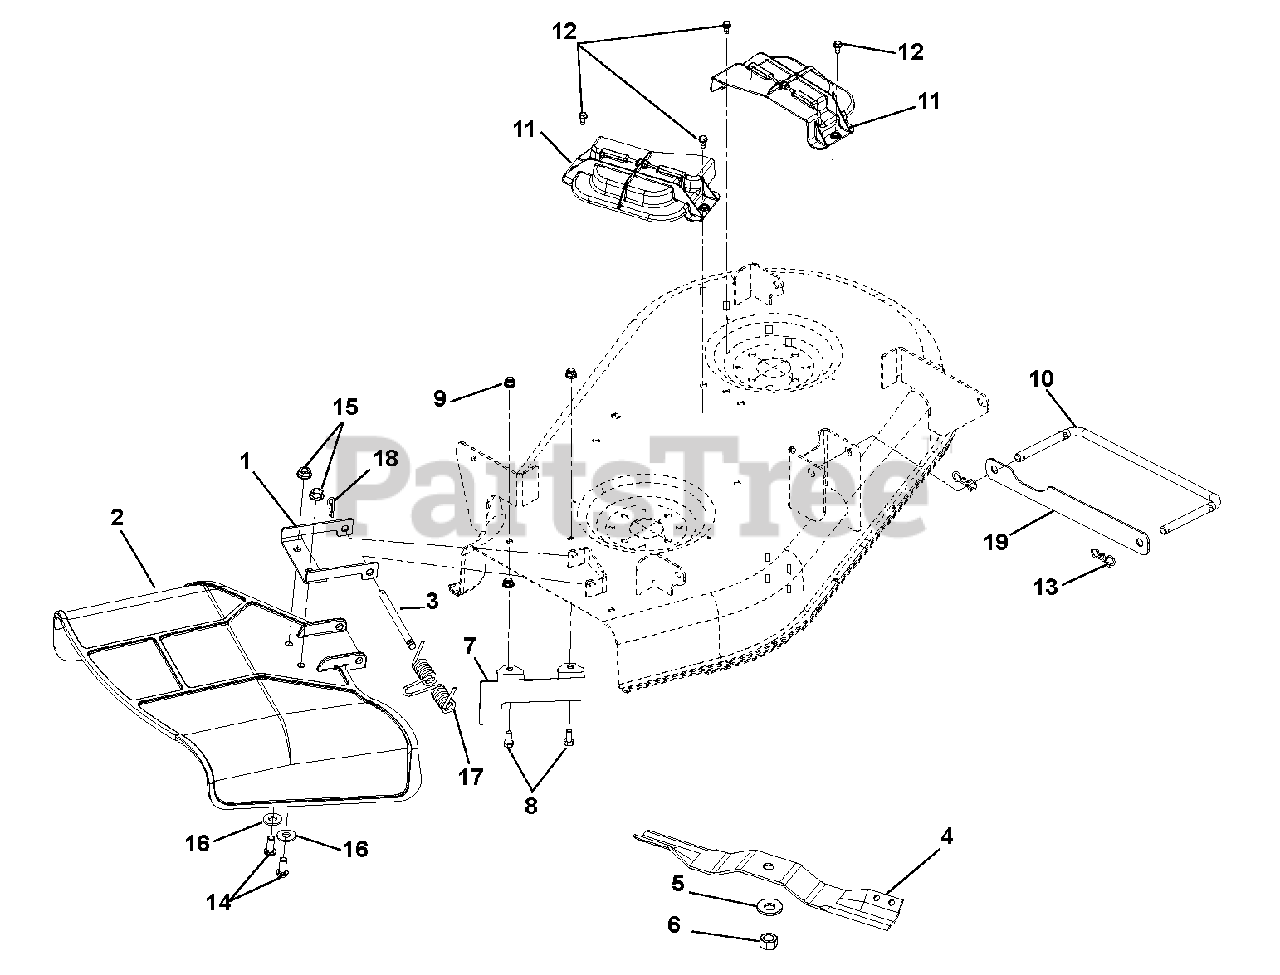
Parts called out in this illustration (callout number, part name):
1	Chute Reinforcement
2	Molded Chute
3	Pin, 5/16 x 3.88"
4	Blade, 17.34 OS Mulch
5	Washer, Beveled .63 x 1.625 x .14
6	Nut, Hex .62-18
7	Bracket, Baffle Discharge 34"
8	Bolt, Hex .31-18 x .75
9	Nut, .31-18 Nyloc Flange
10	Wireform, Drag Link
11	Molded Cover, Belt
12	Screw, Tapping .25-20 x .50 Hex Washer Head
13	Pin, Bow Tie Locking Cotter .091 x 1.875
14	Screw, .31-18 x .75
15	Nut, Locking Top Flange .31-18
16	Washer, Flat Steel .38 x .875 x .083
17	Spring, Torsion
18	Pin, Hair .08 x .18 x 1.18
19	Strap, Drag Link
